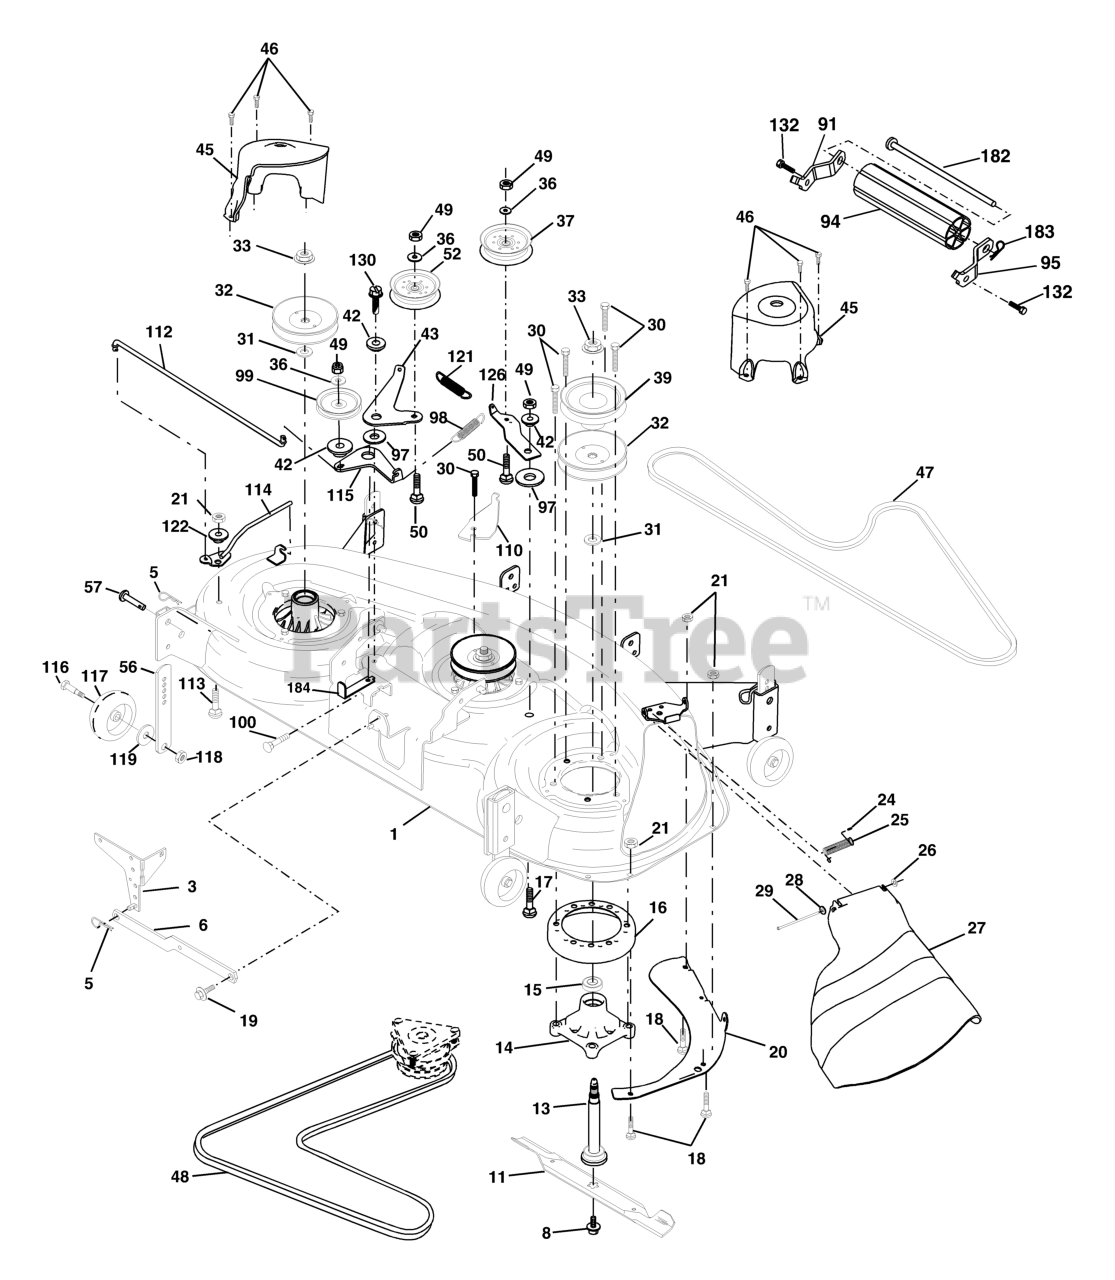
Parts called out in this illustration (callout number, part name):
1	DECK WELDMENT MOWER, 48
3	BRACKET ASM.
5	RETAINER-SPRNG RB
6	BAR SWAY DECK
8	BOLT 7/16 ASM BLADE
11	48" HI-LIFT BLADE
13	SHAFT ASM W/LOWER BEARING
14	HOUSING, MANDREL 48"
16	STRIPPER.MANDREL.ROUND.BLACK
17	BOLT
18	BOLT
19	BOLT SHD 5/16-18
20	BAFFLE, VORTEX MWR
21	LOCKNUT
24	CAP-SLEEVE LT
25	SPRING, TORSION
26	NUT PUSH M
27	DEFLECTOR SUBS TO 532 180655
28	Washer 11/32 x 5/8 x 16 Ga.
29	ROD.HINGE
30	SCREW, WASHER HEAD
31	WASHER
32	PULLEY, MANDREL
33	NUT, FLG TOPLOCK 9/16"
36	WASHER
37	PULLEY.IDLER.FLAT
39	PULLEY.DRIVEN.DECK.48'
42	SPACER RETAINER
43	ARM, IDLER SECONDARY
45	COVER, MANDREL DECK
46	SCREW.1/4-20X5/8
47	V-BELT, MWR SECONDARY
48	V-BELT PRIMARY 48"
50	BOLT.3/8-16X1.50
52	PULLEY.IDLER.FLAT.46.PR.DR.
56	BAR.ADJUST.WHEEL.ANTI.SCALP.BL
57	RIVET.PIN.HEAD.YELLOW.
91	BRKT.NOSEROLLER.LH.48"
94	NOSE ROLLER 48"
95	BRKT.NOSEROLLER.RH.48"
97	HARDENED WASHER
98	SPRING PRIMARY DRIVE
99	PULLEY,IDLER"V"
100	BOLT
107	BAFFLE.VAC.EDGE.MOWER.48"
108	BOLT
109	NUT.CROWNLOCK.1/4
110	ARM, SPRING SECONDARY
112	LEVER, TENSION RELIEF LINK
113	BOLT CRT
114	LEVER ASM, TENSION RELIEF
115	ARM, SPRING TENSION RELIEF
116	BOLT, SHOULDER
117	WHEEL GAGE DONUT
118	LOCKNUT
119	WASHER.5/16.FLAT.STE.STD.
121	SPRING.DRIVE.SECONDARY.48".DEC
122	BUSHING, PIVOT TENSION RELIEF
126	ARM, IDLER PRIMARY DECK
130	SCREW 3/8-16X1
132	SCREW 3/8-16X3/4
182	ROD.ROLLER.NOSE.NARROW.48"
183	SPRING RETAINER
184	KEEPER BELT IDLER PLATED
